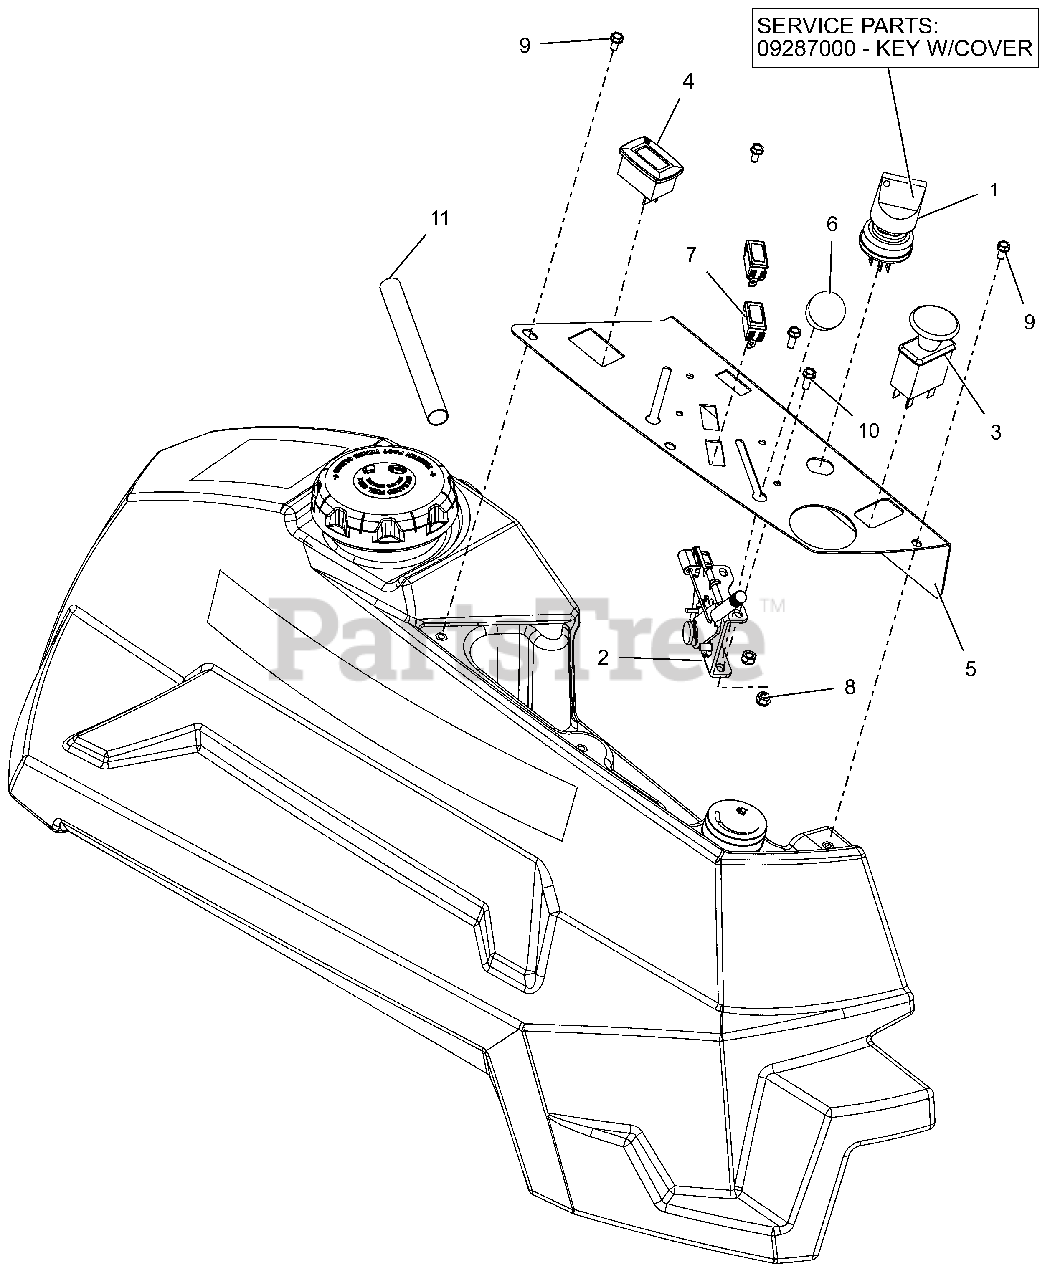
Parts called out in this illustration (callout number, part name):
1	SWITCH, IGNITION
1	KEY, W/ SHIELD
2	CABLE, PRO-CTRL 43.00"
3	SWITCH, CLUTCH
4	METER, HOUR W/MAINTENANCE
5	PT400 CONTROL PANEL - RED
6	KNOB-CONTROL-BLACK .38-16X.50
7	LIGHT,INDICATOR
8	@NUT-LK-NYL 10-24 W/INSRT YWZC
9	SCR-MCH 10-24X.38 HWHSTAINLESS
10	@SCR-MCH 10-24X.50 HWH YWZC
11	SLEEVE, THERMAL 6"
